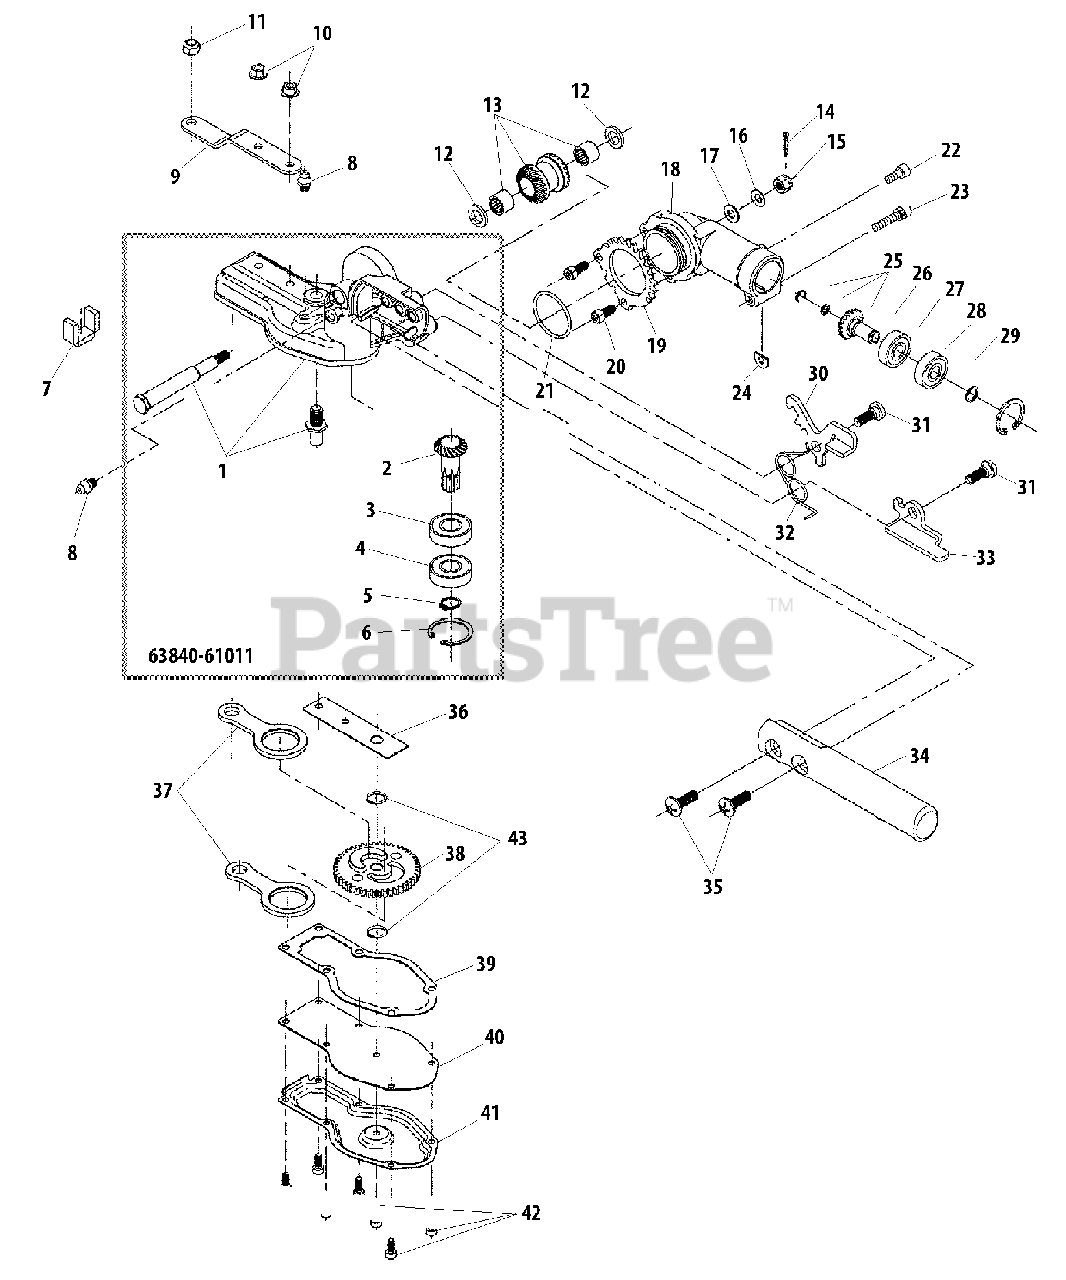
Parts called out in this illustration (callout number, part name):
1	GEAR CASE HOUSING ASSY
2	SHAFT, PINION
3	BEARING, BALL 6001
4	BEARING, BALL 6001ZZ
5	RING, SNAP Ø12
6	RING, SNAP Ø28
7	PACKING, FELT
8	FITTING, GREASE
9	BRACKET, CUTTER
10	NUT, FLANGE M5
11	NUT, LOCK M6
12	COLLAR Ø16ר10×L= 2
13	GEAR, BEVEL
14	PIN, COTTER Ø1.6×15
15	NUT M6
16	WASHER, CONE M6
17	WASHER 6.5×13×1
18	HOUSING, UPPER GEAR CASE
19	RING, LOCKING
20	BOLT 5×12
21	O-RING
22	BOLT 5×12
23	BOLT M5×25
24	D-WASHER
25	PINION SET, BEVEL
26	BEARING, BALL 609
27	BEARING, BALL 609ZZ
28	RING, SNAP
29	RING, SNAP Ø24
30	LEVER, LOCK
31	BOLT M6
32	SPRING, TORSION
33	RELEASE, LOCK
34	LEVER, ADJUSTMENT
35	SCREW, TRUSS M6×20
36	PLATE, GUIDE
37	CONROD
38	GEAR, CAM
39	GASKET, GEAR CASE
40	SPACER
41	COVER, GEAR CASE
42	BOLT 4×10
43	SPACER Ø11ר8×3.4
63840-61011	GEAR CASE HOUSING KIT
